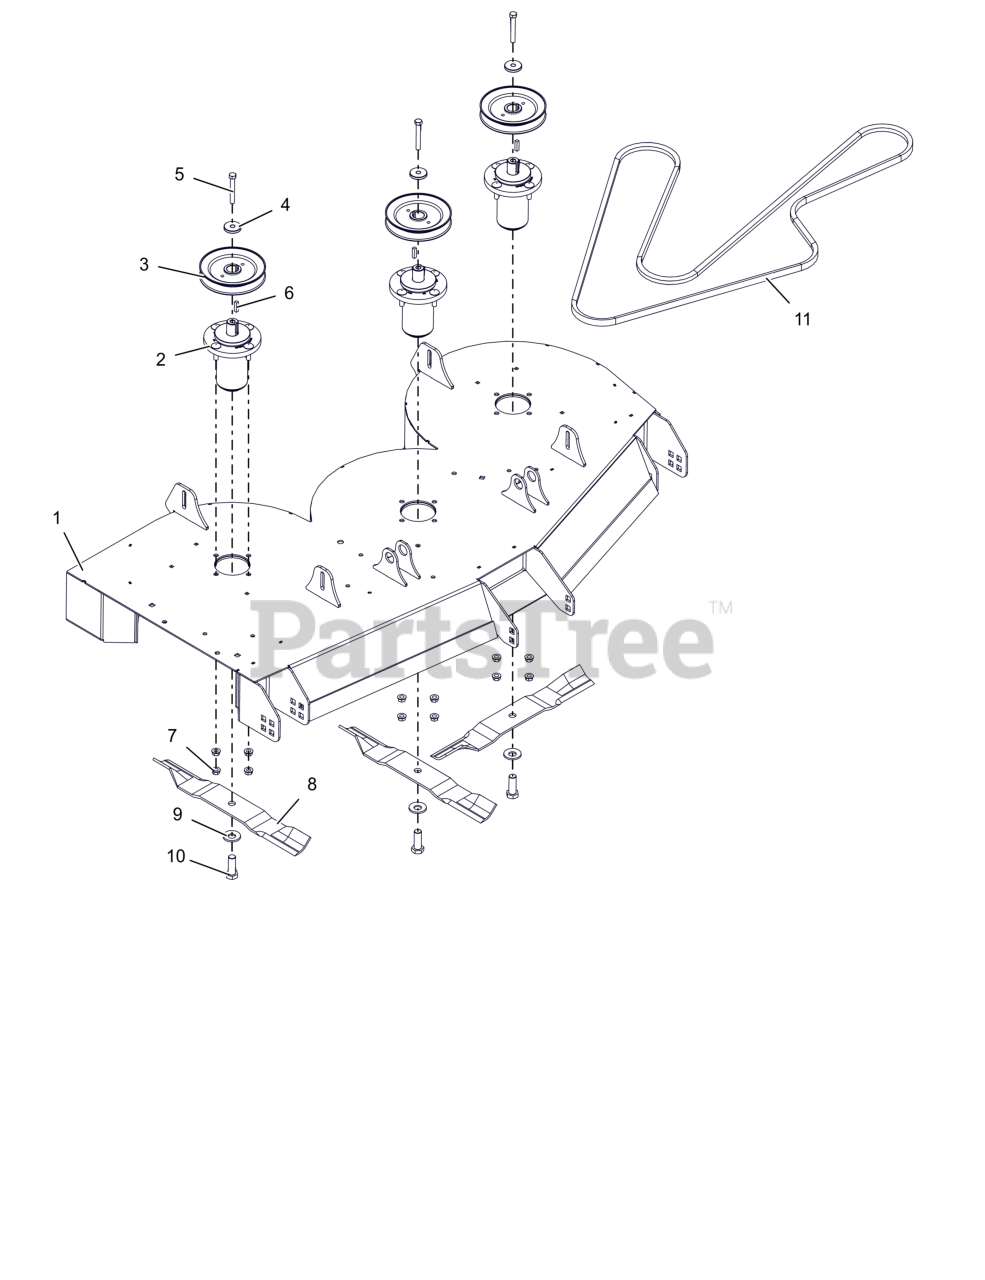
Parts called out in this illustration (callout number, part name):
1	52" DECK WLDMT W/SAFETY DECALS
2	ASM, MAINT FREE ALUM SPINDLE
3	PULLEY, V - 1.000 ID X 5.750 OD
4	RETAINER, SHEAVE
5	BLT, HEX .38-16X2.75 G8 ZCC
6	KEY, SQ .25X.25X1.00 RC 40-50
7	NUT-LK-CTR-FLG .375-16 GF ZCC
8	BLADE, 18"
9	WSHR-BLVL .669X1.535X.138
10	BLT, HEX .62-18X1.75 G8 ZCC
11	V-BELT, B RAW EDGE EPDM
